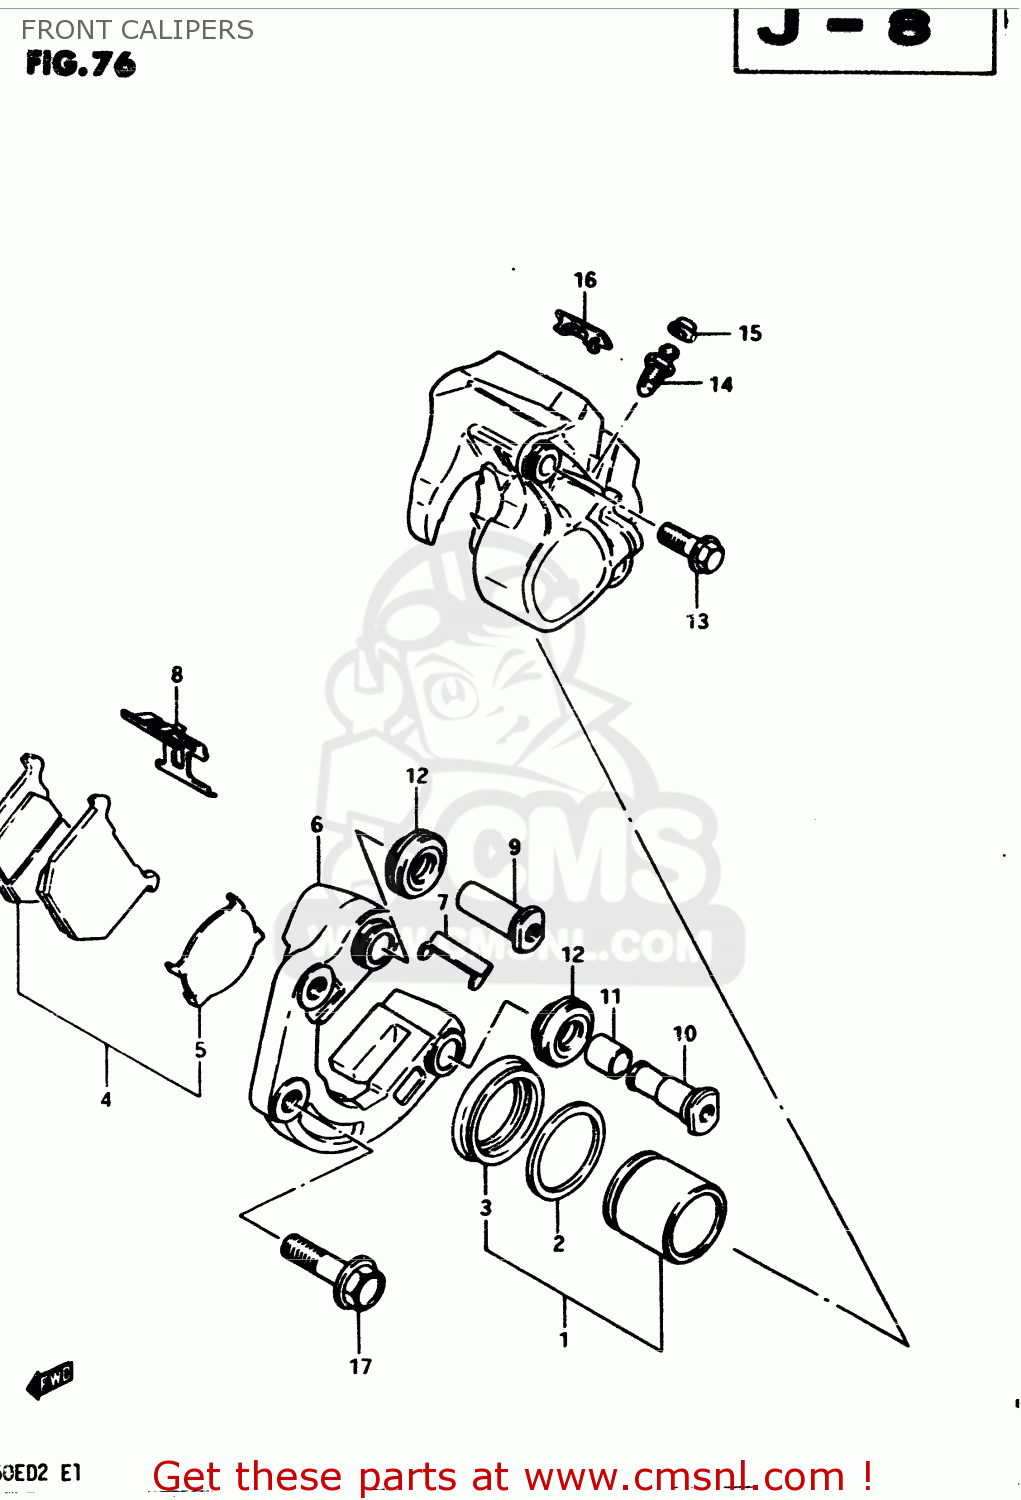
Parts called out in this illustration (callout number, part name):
1	PISTON SET
2	SEAL,FR CALIPE
3	BOOT,PISTON
4	PAD SET (MCA)
5	SHIM,PAD
6	CARRIER,CALIPER,LEFT
7	GUIDE,PAD
8	SPRING,PAD
9	AXLE NO.1
10	AXLE NO.2
11	BUSH,AXLE
12	BOOT,AXLE
13	BOLT
14	BLEEDER
15	CAP,BREATHER
16	COVER
17	BOLT 10X37
